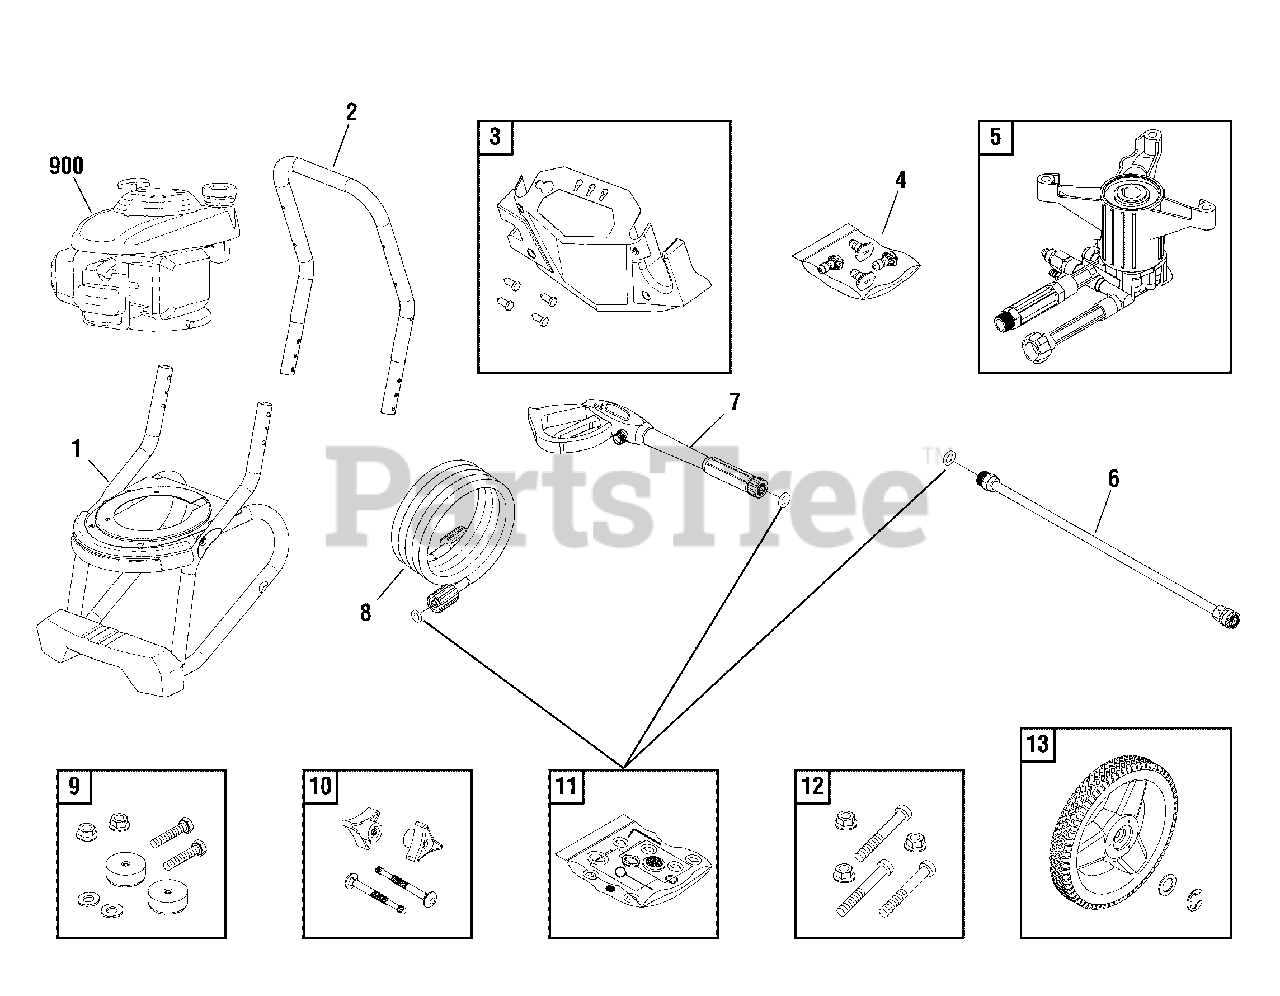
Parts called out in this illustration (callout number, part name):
6	GUN
7	EXTENSION-QC
8	HOSE
9	MOUNT-VIBRATION
10	KIT-HARDWARE HANDLE
12	KIT-HARDWARE PUMP MOUNTING
900	** ENGINE
